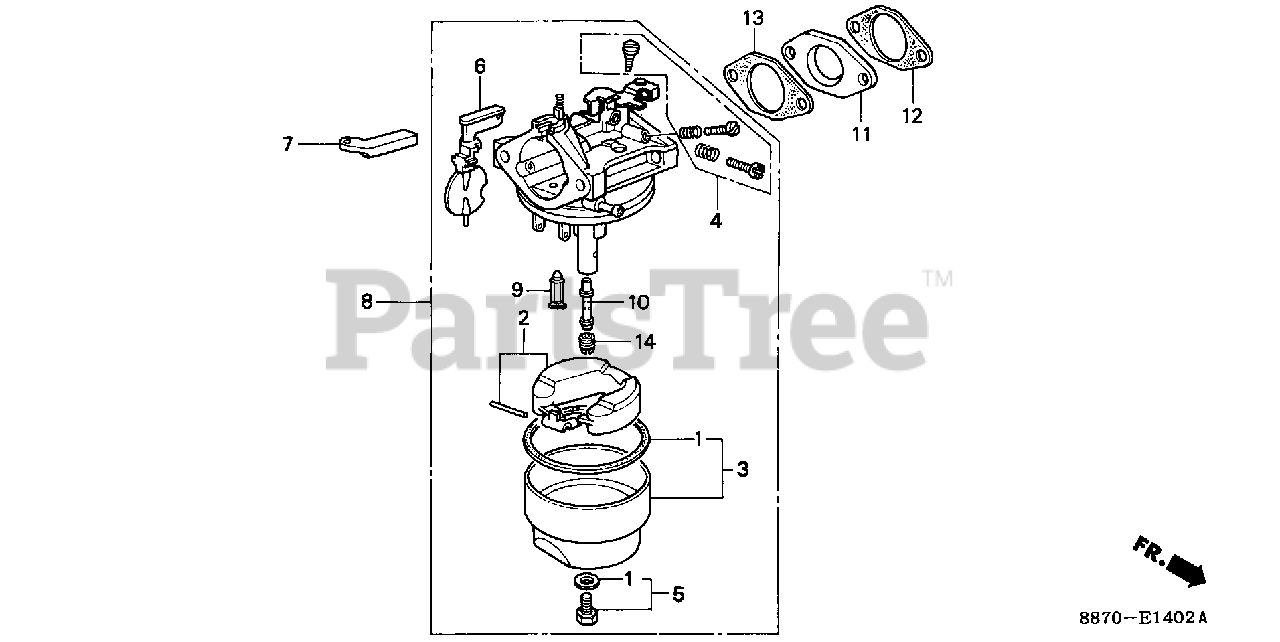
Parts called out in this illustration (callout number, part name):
1	GASKET SET (CARBURETOR NO.)
2	FLOAT SET (CARBURETOR NO.)
3	CHAMBER SET, FLOAT (CARBURETOR NO.)
3	CHAMBER SET, FLOAT (CARBURETOR NO.) (NOT AVAILABLE)
4	SCREW SET A (CARBURETOR NO.)
5	SCREW SET (CARBURETOR NO.)
5	SCREW SET
6	CHOKE SET (CARBURETOR NO.)
7	ARM, CHOKE LEVER
8	CARBURETOR ASSY. (BB28B C)
9	VALVE, FLOAT (CARBURETOR NO.)
10	NOZZLE, MAIN (CARBURETOR NO.)
11	INSULATOR, CARBURETOR
12	GASKET, INSULATOR
13	GASKET, CARBURETOR
14	JET, MAIN (#55) (CARBURETOR NO.)
14	JET, MAIN (#58) (CARBURETOR NO.)
14	JET, MAIN (#60) (CARBURETOR NO.)
14	JET, MAIN (#62) (CARBURETOR NO.)
14	JET, MAIN (#65) (CARBURETOR NO.)
